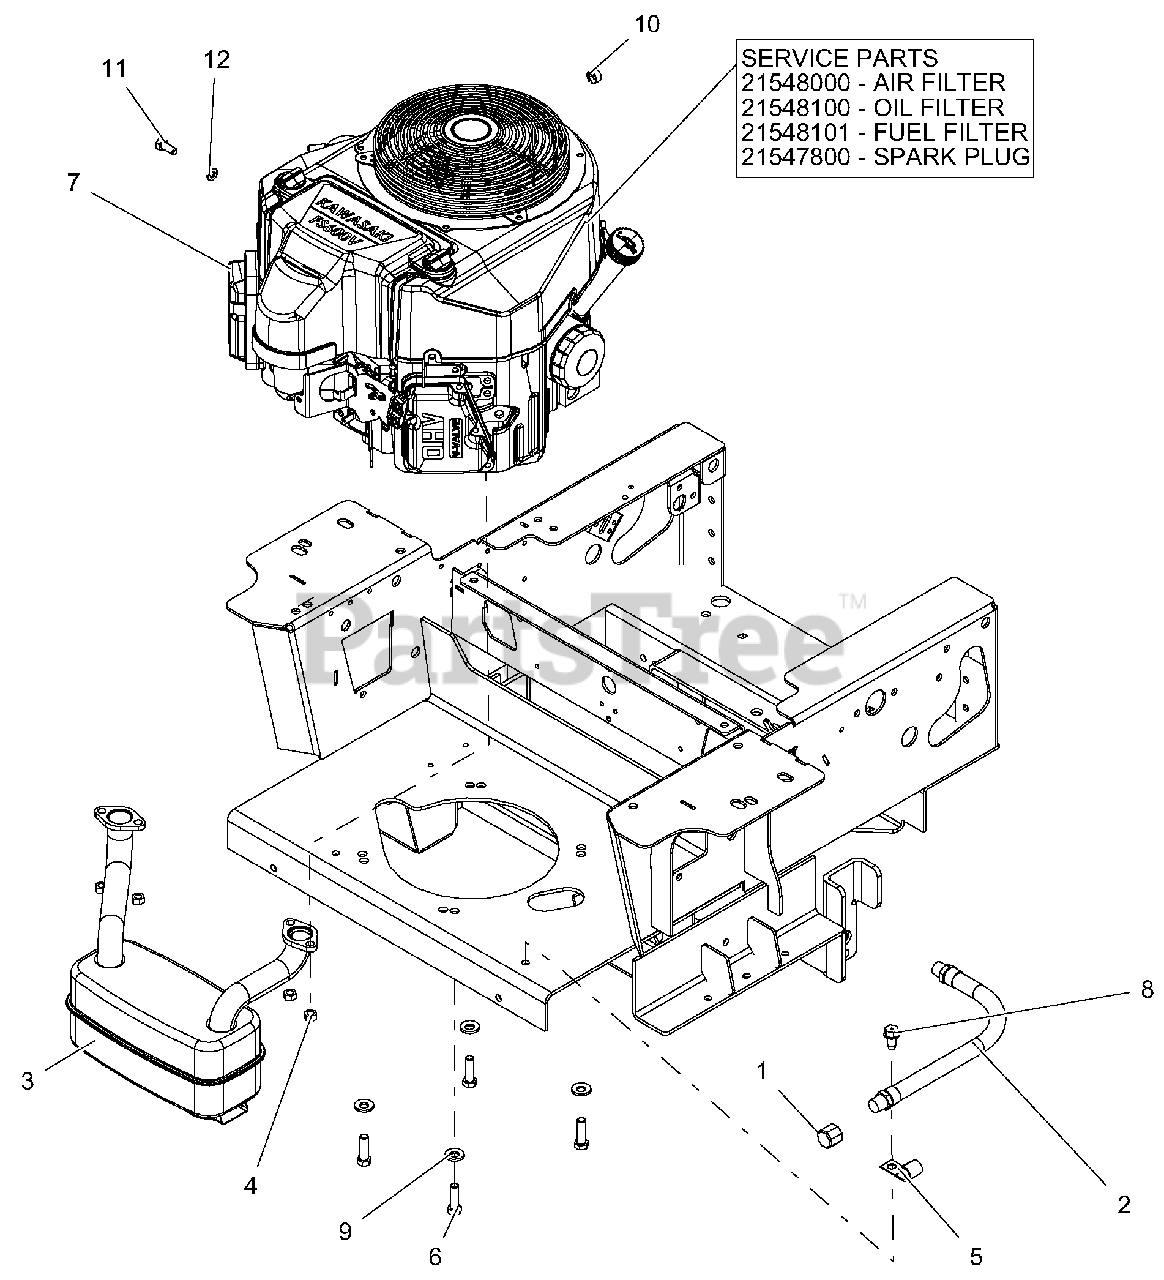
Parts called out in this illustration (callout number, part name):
1	PIPE, CAP 3/8 NPT FEMALE
2	HOSE, HYD .38-11-OK M6N0-M6N0
3	MUFFLER, KAWASAKI
4	NUT-LK-TOP M8-1.25 YWZC
6	BLT-HEX .38-16X1.25 GR5 YWZC NYTORQ
7	ENGINE, KAWASAKI FS691
7	OIL FILTER
7	FUEL FILTER
7	SPARK PLUG
7	AIR FILTER
8	SCR-TAP .38-16X.75 HWH TR YWZ
9	WSHR, 3/8" SPRING DISC
10	CLAMP, FUEL LINE
11	@BLT-HEX M8-1.25X20 YWZC
12	WSHR-LK .31X.078 REG YWZC
